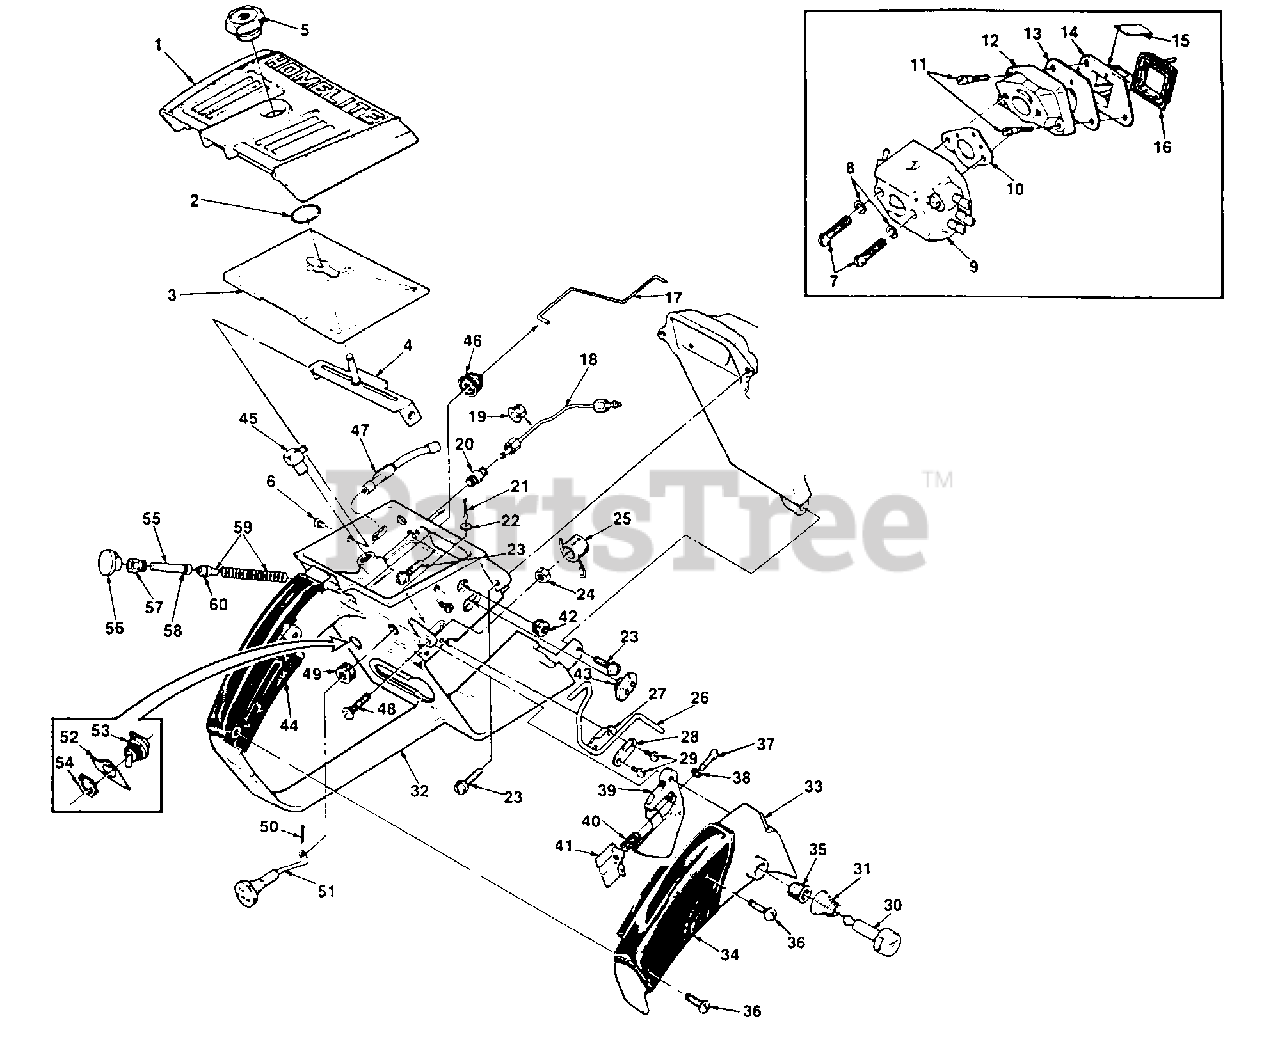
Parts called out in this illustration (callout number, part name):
1	COVER- Air filter
2	RING- Retaining
3	FILTER ELEMENT- Air
4	BRACKET- Air filter cover
5	NUT- Cover mounting (1/4-28)
6	SCREW- Pan, 8-32 x 3/8
7	SCREW- Hex, 10-32 x 1 5/8
8	WASHER- Lock #10
9	CARBURETOR- (HDC-64)
10	GASKET- Carburetor
11	SCREW- Shoulder
12	MANIFOLD- Intake
13	GASKET- Reed valve seat
14	SEAT- Reed valve
15	REED- Valve
16	RETAINER- Reed valve
17	ROD- Throttle
18	LINE- Oil
19	GROMMET- Oil line
20	VALVE- Check (outlet)
21	PIN- Cotter, 1/16 x 1/2
22	WASHER- Felt
23	SCREW- Hex, 12-24 x 5/8
24	NUT- hex, 10-32
25	SPRING- Release valve
26	LEVER- Release
27	PLATE- Lever
28	CLAMP- Lever
29	SCREW- Pan 6-32 x 3/8
30	PIN- Trigger latch
31	SPRING- Throttle latch
32	HANDLE- Throttle
33	COVER- Throttle handle
34	GRIP- Throttle handle cover
35	BUSHING
36	SCREW- Pan, 8-32 x 1/2
37	SCREW- Pan 6-40 x 1
38	"O" RING
39	TRIGGER- Throttle
40	SPRING- Throttle stop
41	STOP- Throttle adjustment
42	GROMMET- Idle adjusting
43	GROMMET- "Hi-Lo"
44	GRIP- Throttle handle
45	VALVE- Check (inlet) 90ø
46	BOOT- Throttle rod
47	LINE- Oil
48	SCREW- Round hd., 10-32 x 7/8
49	GROMMET- Choke
50	PIN- Cotter, 1/32 x 1/2
51	ROD- Choke
52	PLATE- "On-Off"
53	SWITCH- Grounding
54	NUT- Lock
55	PLUNGER- Oil pump
56	BUTTON- Oil pump
57	NUT- Plunger
58	"O" RING
59	PLUNGER- Pump
60	"O" RING
